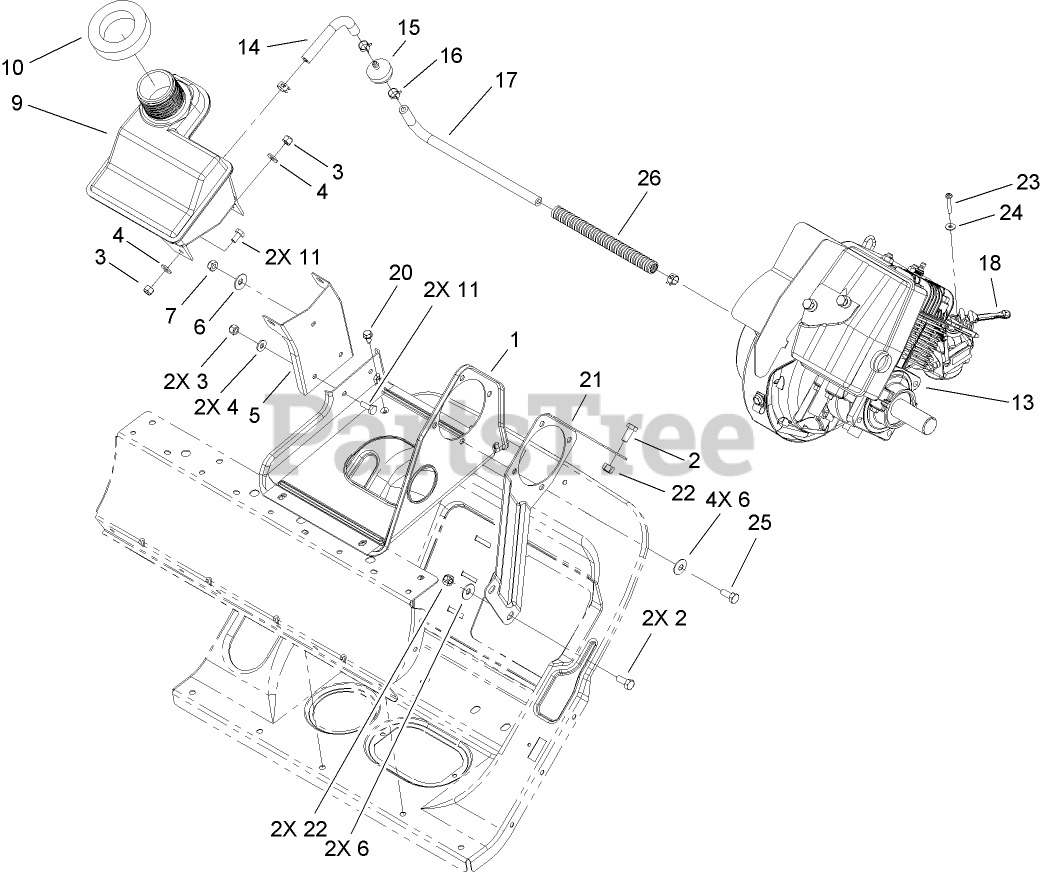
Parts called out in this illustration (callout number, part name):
2	SCREW-HH
3	NUT-LOCK, NI
4	WASHER-FLAT
5	SUPPORT-RECOIL
6	WASHER-BELLEVILLE
7	NUT-LOCK, NI
9	TANK-GAS
10	SEAL-FOAM
11	SCREW-HH
13	Loose Parts Package
15	FILTER-FUEL
16	CLAMP-HOSE
17	LINE-FUEL
18	LEVER-CHOKE
20	SCREW-HWH, THREAD ROLL
21	BRACE-ENGINE
22	NUT-LOCK, NI
23	SCREW-PPH, PLASTITE
24	WASHER-FLAT
25	SCREW-HH
26	CONDUIT
